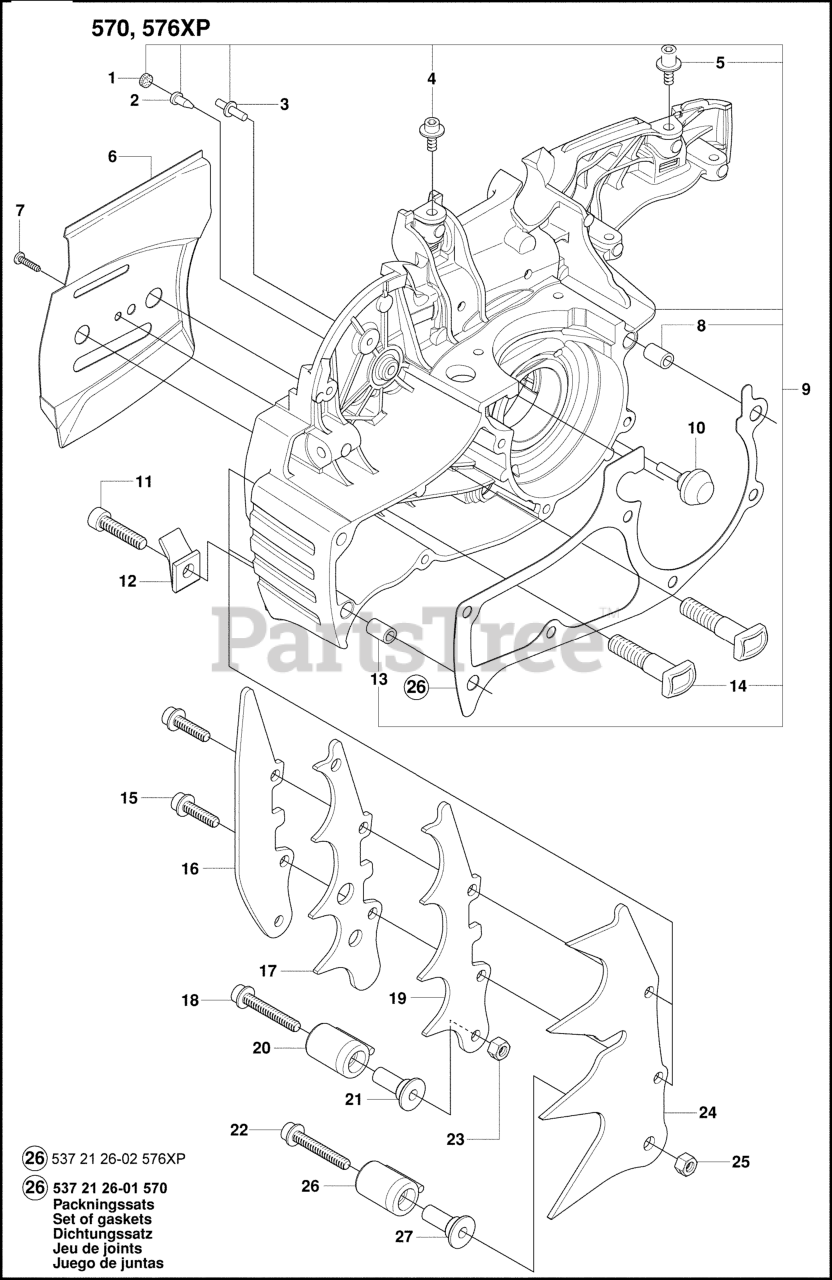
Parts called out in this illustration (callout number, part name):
1	PLUG
2	VALVE-CHECK (DUCKBILL)
4	SCREW IHSCM
5	SCREW IHSCM
8	SLEEVE
9	RP CRANKCASE ASSEMBLY
9	CRANKCASE ASSY
12	CHAIN CATCHER
13	SLEEVE
17	FELLING DOG
19	FELLING DOG
21	CHAIN CATCHER
22	SCREW
24	FELLING DOG
26	GASKET SET
26	GASKET KIT
